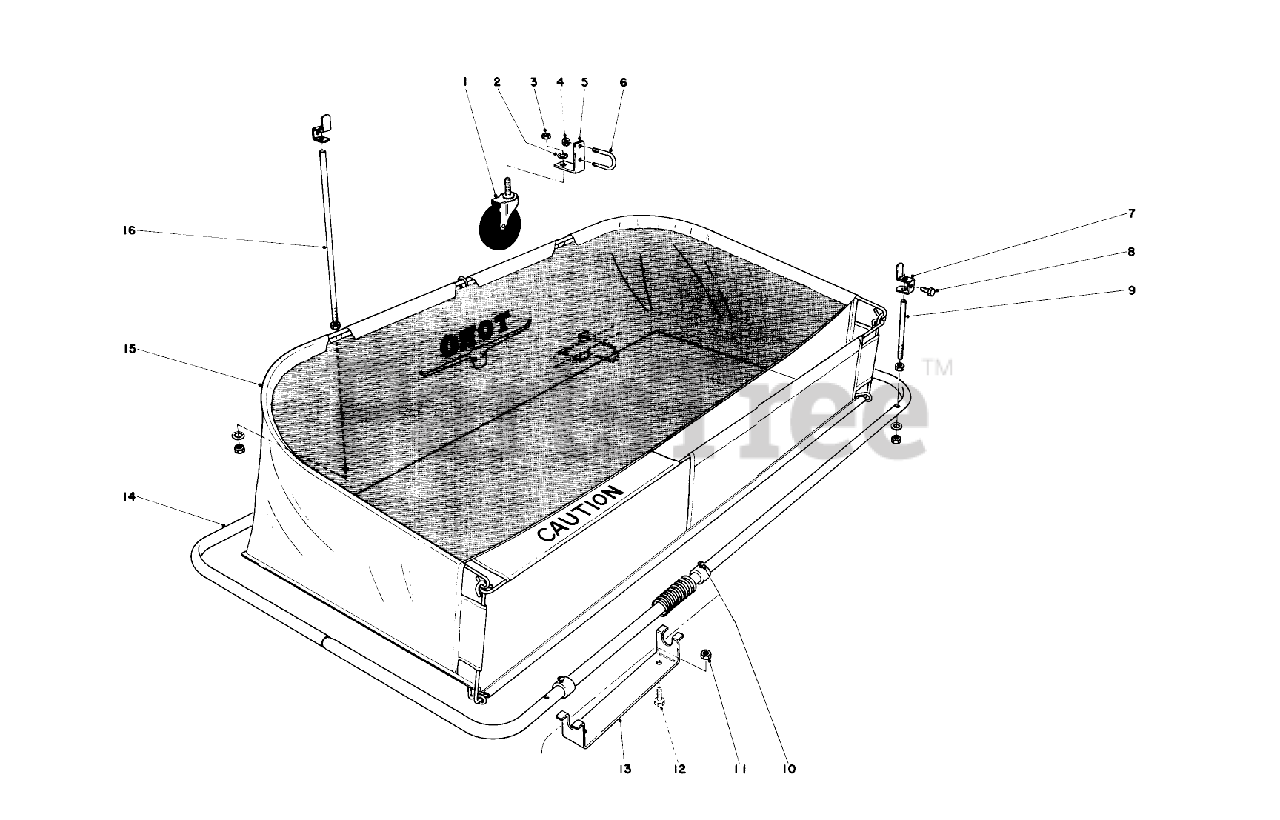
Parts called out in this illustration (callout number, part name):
1	Caster
2	WASHER-LOCK, INTERNAL
3	NUT-HEX
4	NUT-HEX
5	Bracket, Caster
6	U Bolt
8	SCREW-HH
9	Stud, Short
10	Screw, Machine
11	NUT-HEX, SIDE DEFORM
12	SCREW-HH
13	Bracket, Deck Mounting
14	Frame
15	Basket
16	Stud, Long
